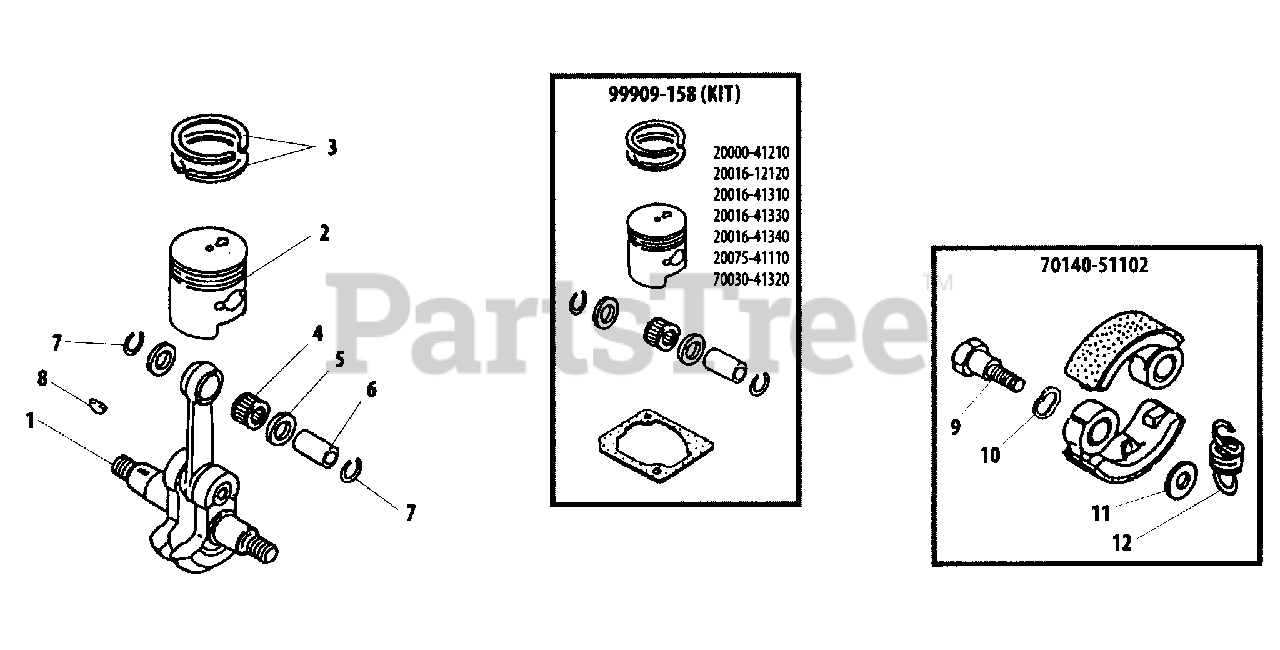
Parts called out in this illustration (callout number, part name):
1	CRANKSHAFT
2	PISTON
3	RING, PISTON
4	BEARING, NEEDLE
5	WASHER, THRUST
6	PIN, PISTON
7	RING, SNAP
8	KEY, WOODRUFF 3×10
9	BOLT, CLUTCH
10	WASHER, SPRING
11	WASHER 6 MM
12	SPRING, CLUTCH
70140-51102	CLUTCH ASSY
99909-158	PISTON ASSY
